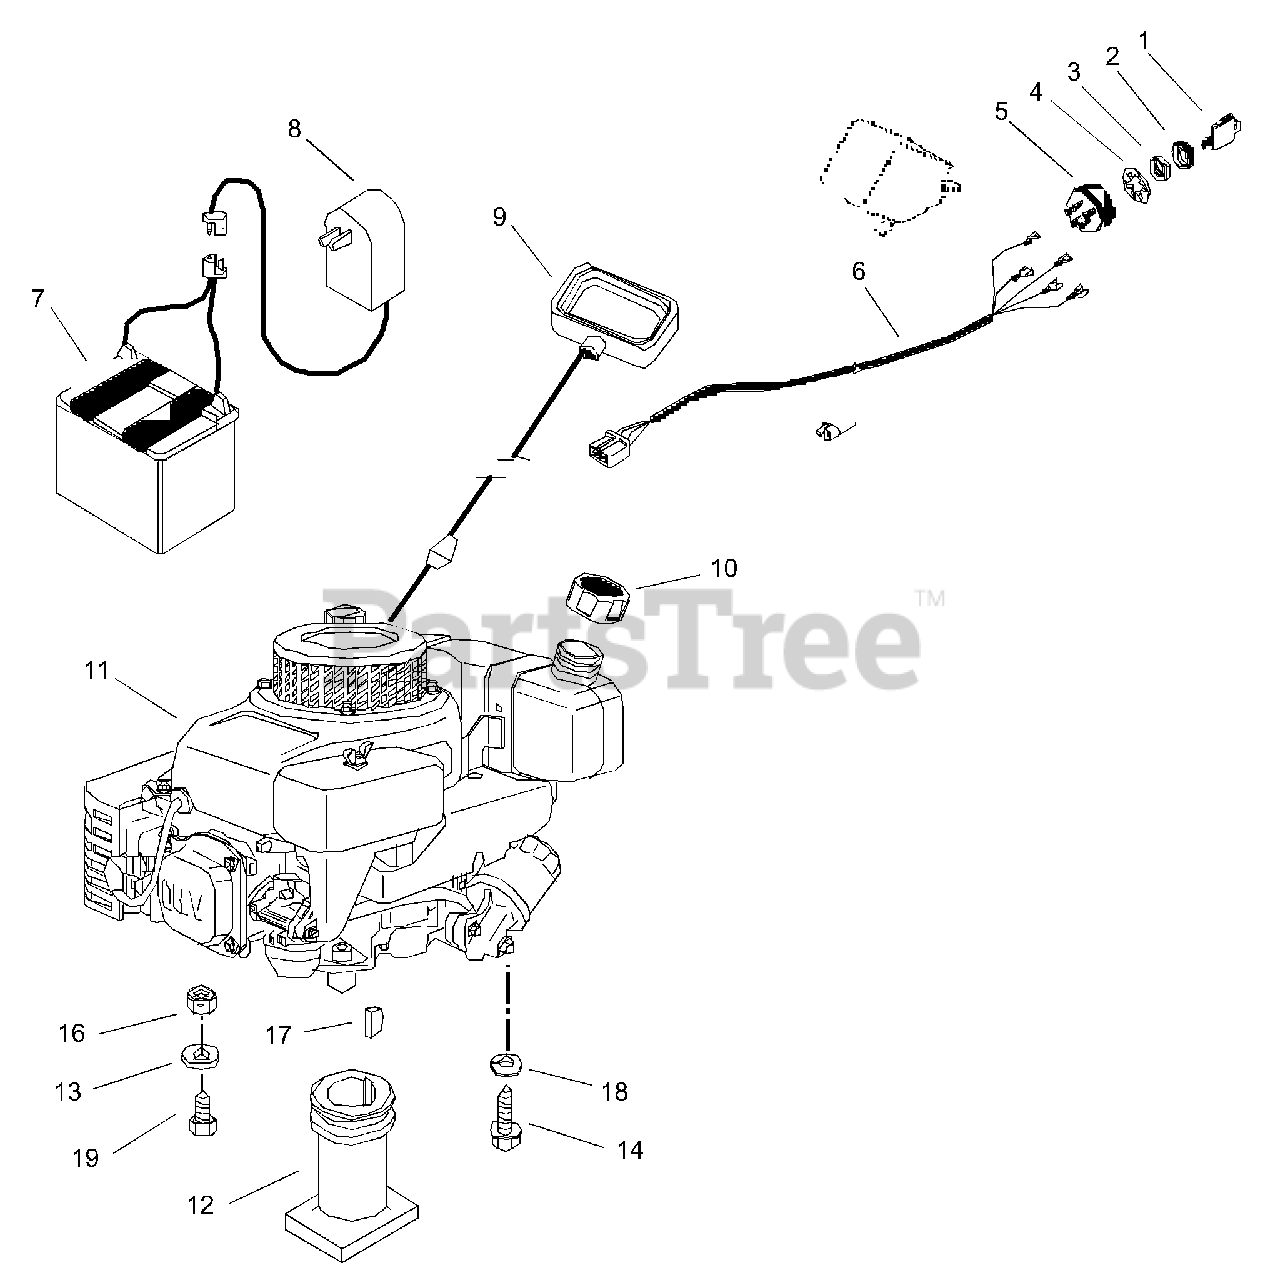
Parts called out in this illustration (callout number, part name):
1	KEY -W/CAP
2	CAP - IGNITION SWITCH
3	NUT-PANEL .625-32 GRECO
4	WSHR-LK-INT .625X.045 YWZC
5	KEY SWITCH
6	WIRE HARNESS
7	BATTERY,
8	BATTERY CHARGER
9	HANDLE, RECOIL START
10	FUEL CAP
11	ENGINE, BRIGG 6.0HP AERO
11	ENGINE, TEC 6.5HP RECOIL MILL
11	ENGINE, TEC 6.5HP EL MILLENNIA
11	ENGINE, BRIGGS 6.5HP INTEK PRO
11	ENGINE ROBIN 6HP. PR LUBE.
12	PLZ READ SERVICE LETTER #L-429
12	BLADE ADAPTER
13	@WSHR-FL-STL.312X.734X.065 YWZ
14	@SCR-TAP .38-16X1.00 HWH TR YZ
15	@BLT-HEX .31-18X.75 GR5 YWZC
16	@NUT-LK-CTR .31-18 YWZC
17	KEY-WDRF .156X.625X.25 SAE 6
18	WSHR-LK .312X.097 HVY YWZC
19	@BLT-HEX .31-18X1.25 GR5 YWZC
